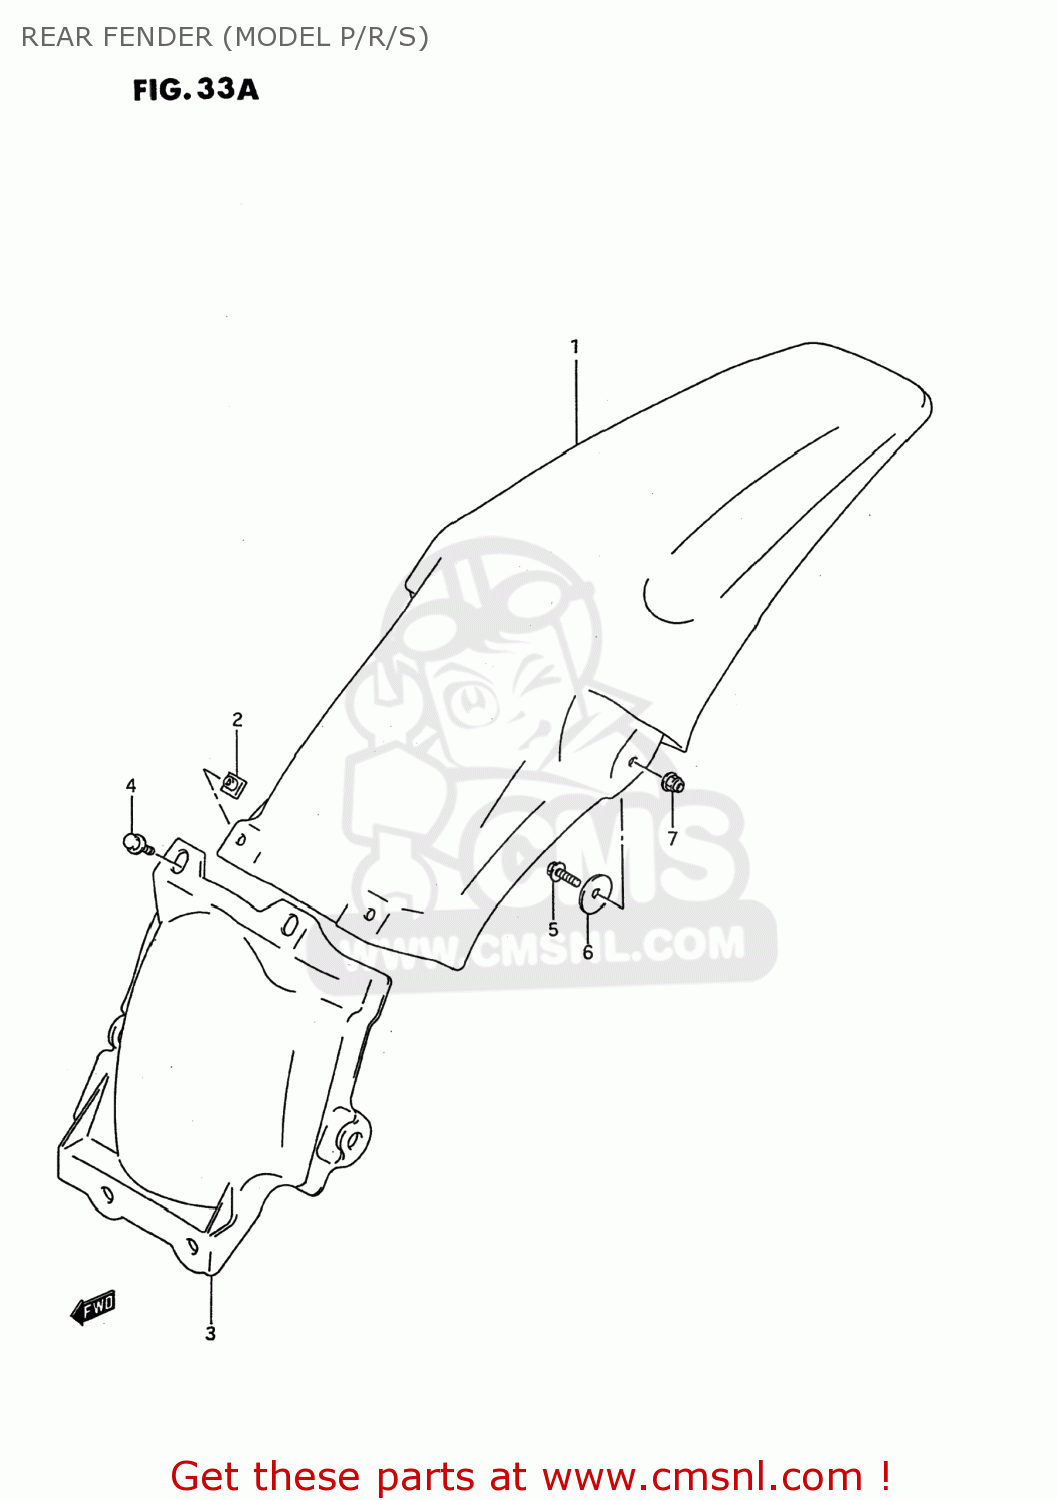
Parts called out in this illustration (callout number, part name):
1	BODY,RR FENDER RR
2	NUT,RR FENDER
3	BODY,RR FENDER FR
4	BOLT
5	BOLT
6	WASHER (6.5X29X1.6)
7	NUT
